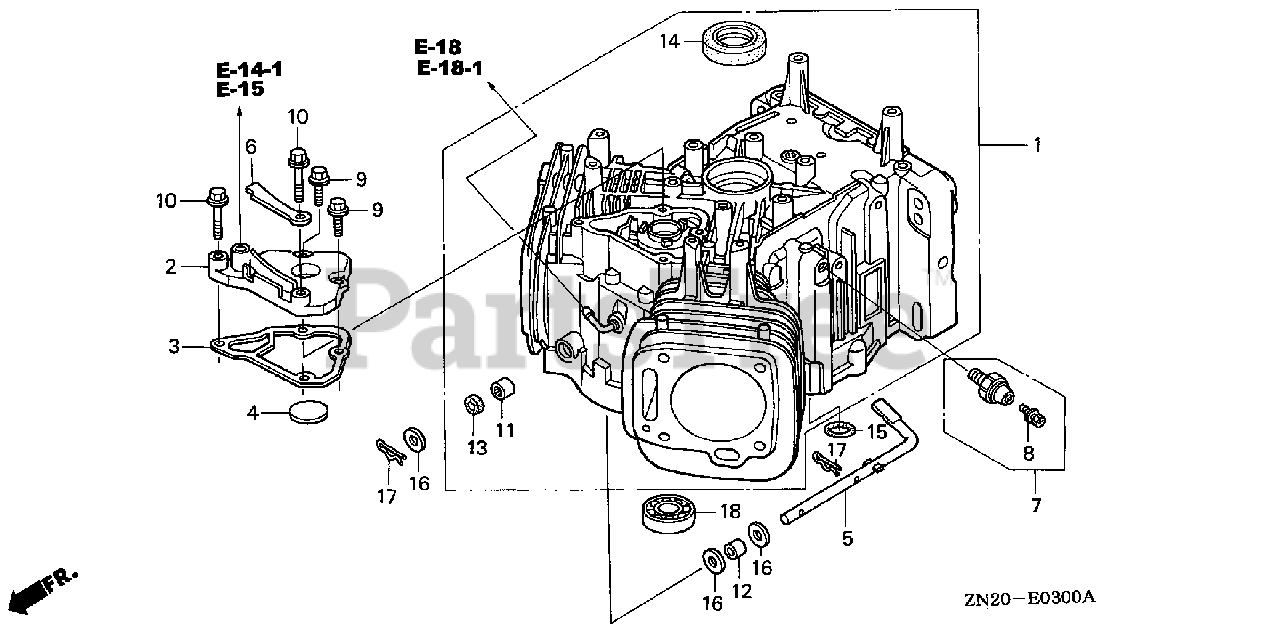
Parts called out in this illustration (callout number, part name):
1	CYLINDER ASSY.
2	COVER, BREATHER
3	GASKET, BREATHER COVER
4	VALVE, BREATHER
5	SHAFT, GOVERNOR ARM
6	CLAMP, WIRE
7	SWITCH, OIL PRESSURE
8	SCREW-WASHER (4X8)
9	BOLT, FLANGE (6X16)
10	BOLT, FLANGE (6X32)
11	BEARING, NEEDLE (8X12.7X11.1)
12	BEARING, NEEDLE (8X12X10)
13	OIL SEAL (8X14X5)
14	OIL SEAL (38X58X9)
15	O-RING (13X3.0)
16	WASHER, PLAIN (8MM)
17	PIN, LOCK (8MM)
18	BEARING, RADIAL BALL (6003)
